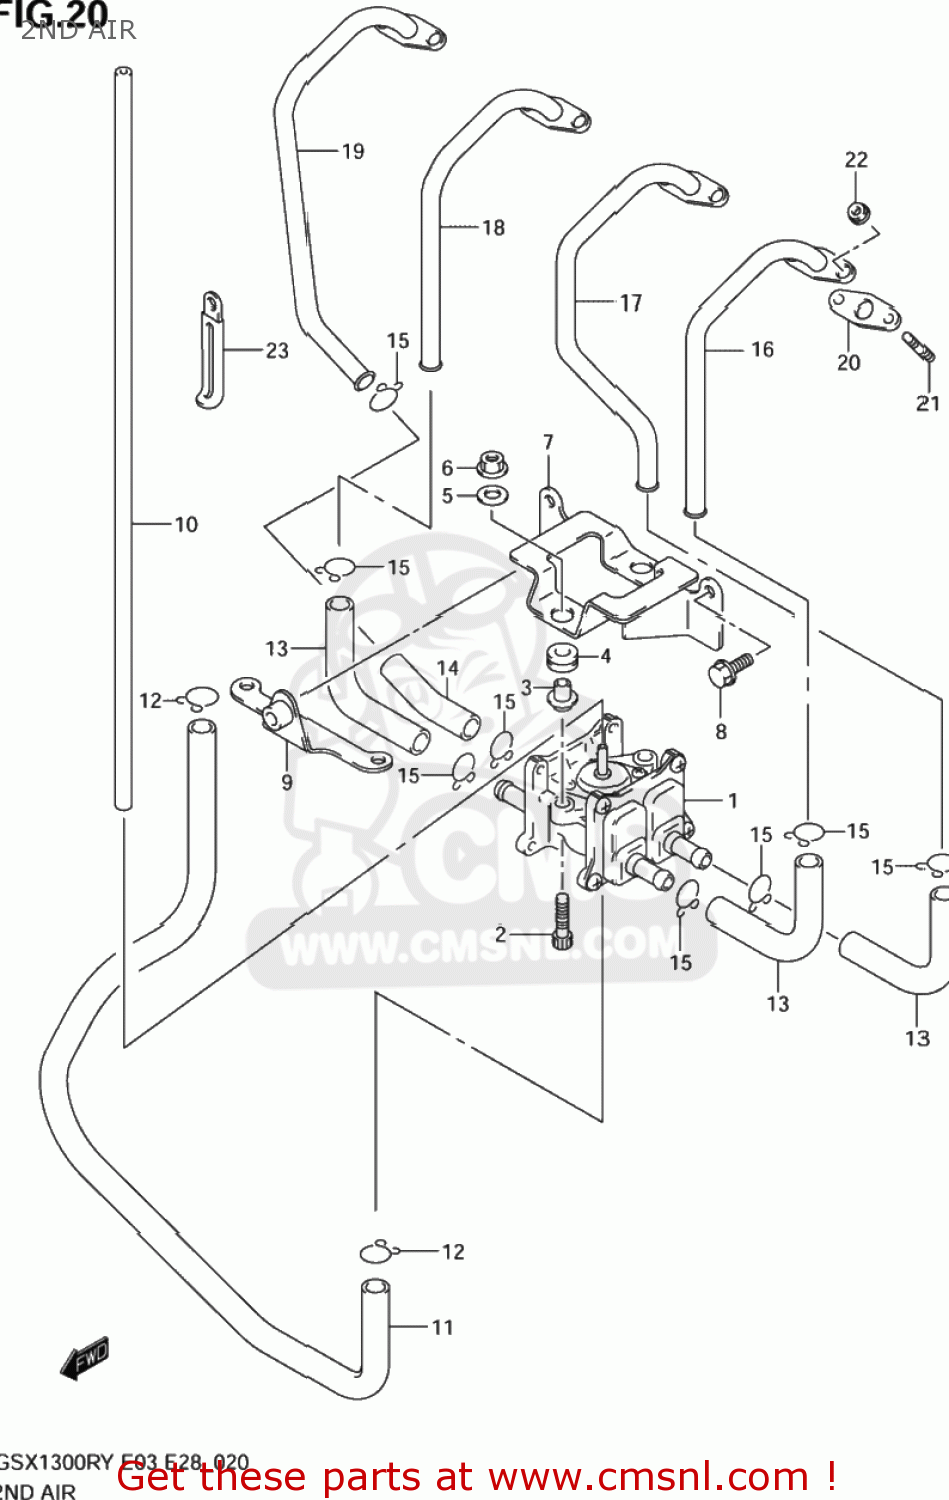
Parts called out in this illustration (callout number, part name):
1	VALVE ASSY,2ND AIR
2	BOLT
3	SPACER,2ND AIR VALVE SPRT
4	CUSHION
5	WASHER(6.5X20X1.6)
6	NUT
7	BRACKET,2ND AIR VALVE
8	BOLT 6X12
9	BRACKET,2ND AIR VALVE BRKT
10	HOSE(3.5X7.5X2000)
11	HOSE,2ND AIR CLEANER
12	CLIP
13	HOSE,2ND AIR VALVE FR
14	HOSE,2ND AIR VALVE,R
15	CLIP
16	PIPE,2ND AIR NO.1,2
17	PIPE,2ND AIR NO.2
18	PIPE,2ND AIR NO.3,4
19	PIPE,2ND AIR NO.4
20	GASKET,2ND AIR PIPE (NAS)
21	STUD BOLT
22	NUT
23	CLAMP(L:65)
